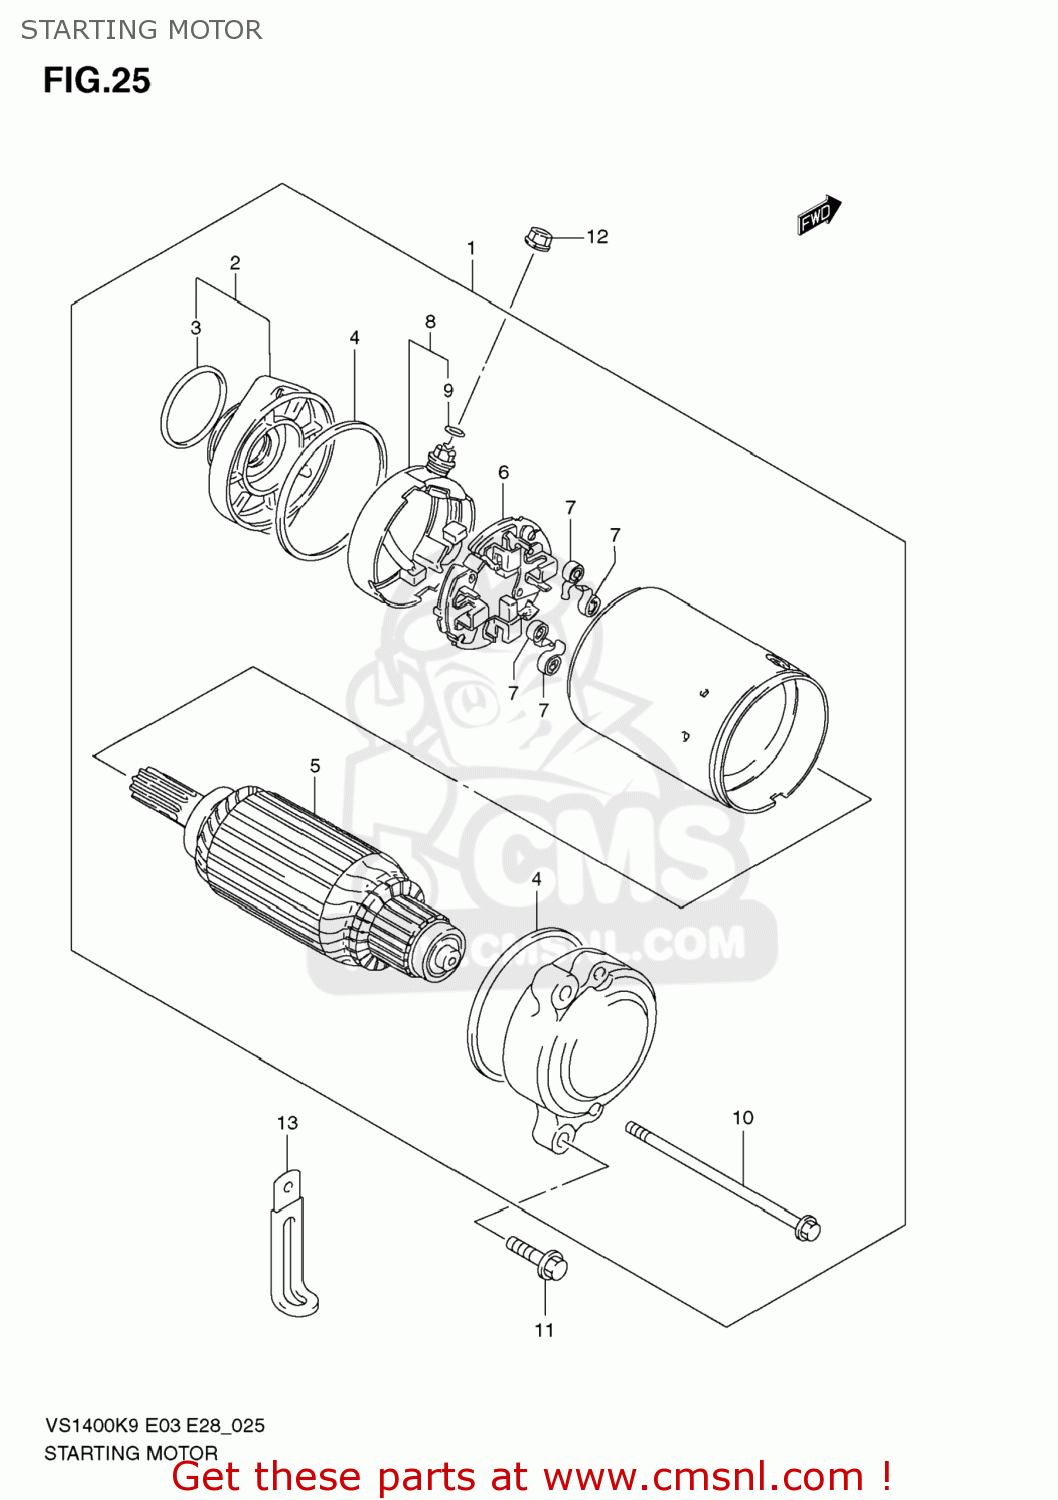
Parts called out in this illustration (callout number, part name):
1	MOTOR ASSY,STARTING
2	BRACKET SET
3	O-RING (D:2.1 ID:34.7)
4	O RING
5	ARMATURE
6	HOLDER SET,BRUSH
7	SPRING,BRUSH
8	TERMINAL SET,BRUSH
9	O RING
10	BOLT
11	BOLT(6X25)
12	NUT
13	CLAMP(L:45)
